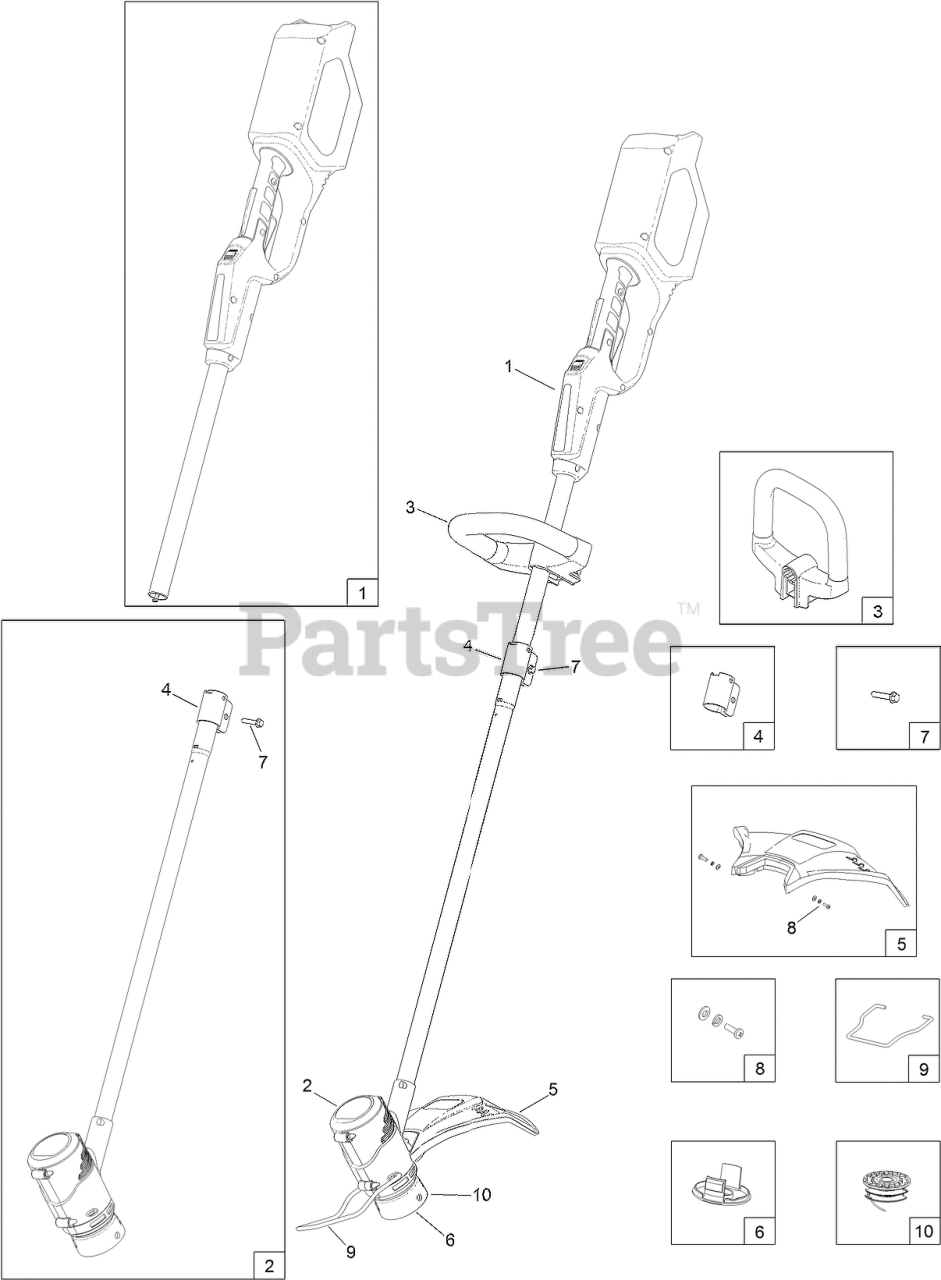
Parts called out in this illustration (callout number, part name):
1	HANDLE-UPPER
2	HOUSING-MOTOR, LOWER
3	HANDLE-ASSIST
4	CLAMP-CONNECTION, SHAFT
5	SHIELD-GRASS
6	CAP-RETAINER, SPOOL
8	SCREW WITH WASHERS ASM
9	WIRE-GUIDE, STRING TRIMMER
10	SPOOL-TRIMMER, SINGLE PACK
